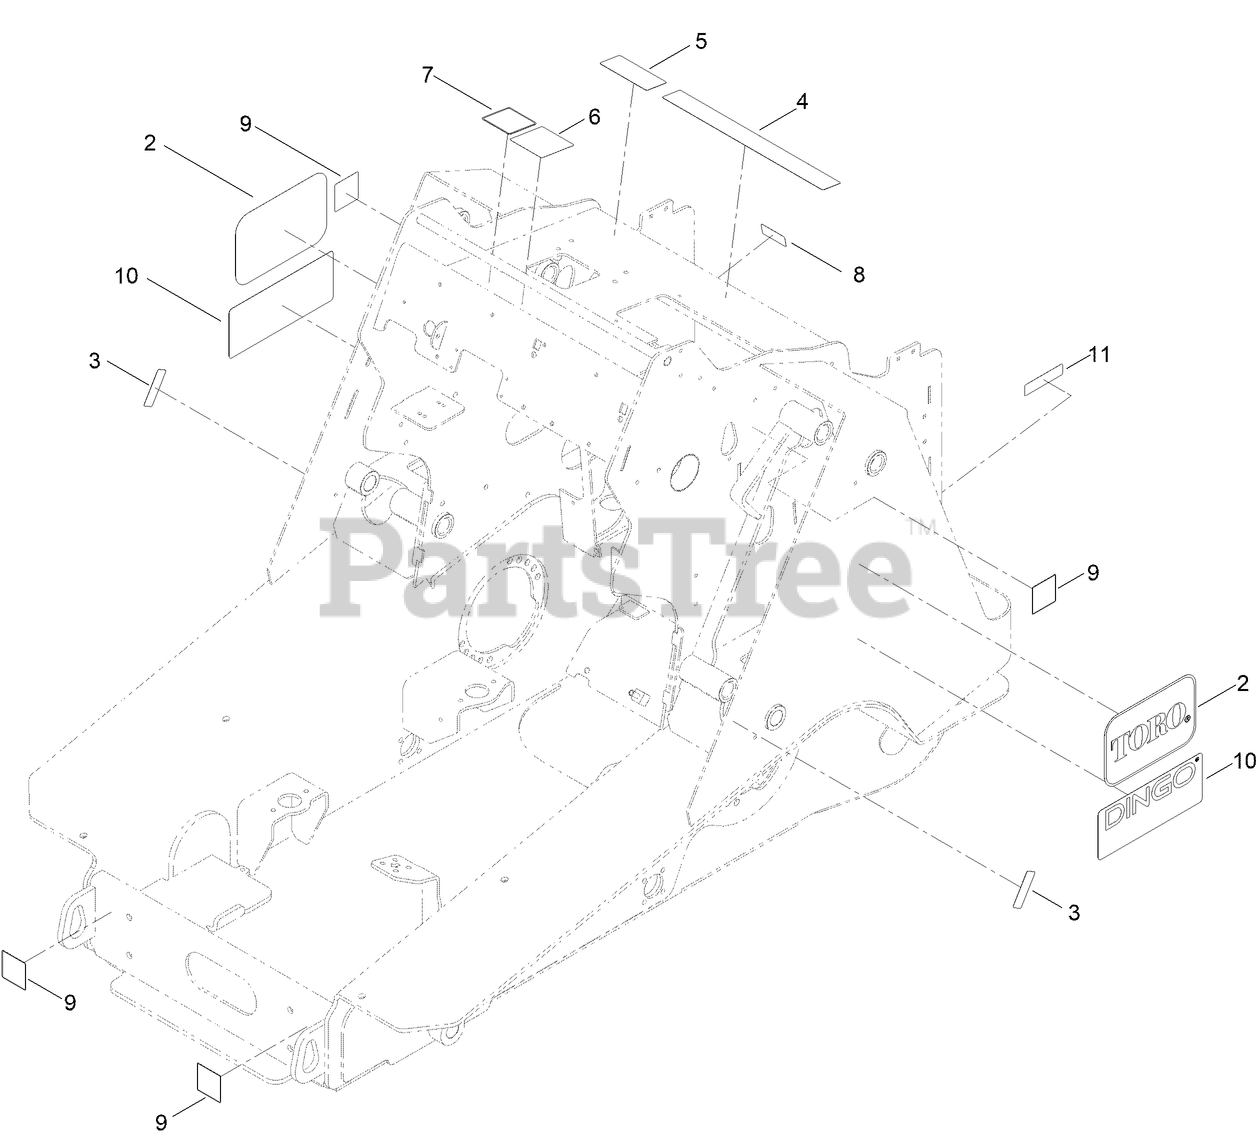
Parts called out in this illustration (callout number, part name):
2	DECAL
3	DECAL-WARNING, PINCH POINT
4	DECAL-SAFETY
5	DECAL-EXTENDED ARM SAFETY
6	DECAL-CONTROL, LOADER
7	DECAL-JOYSTICK CONTROLS
8	DECAL-SURFACE, HOT
9	DECAL-LIFT HERE
10	DECAL-DINGO TX1300
11	DECAL-ARRESTOR, SPARK
12	DECAL-TIE DOWN
